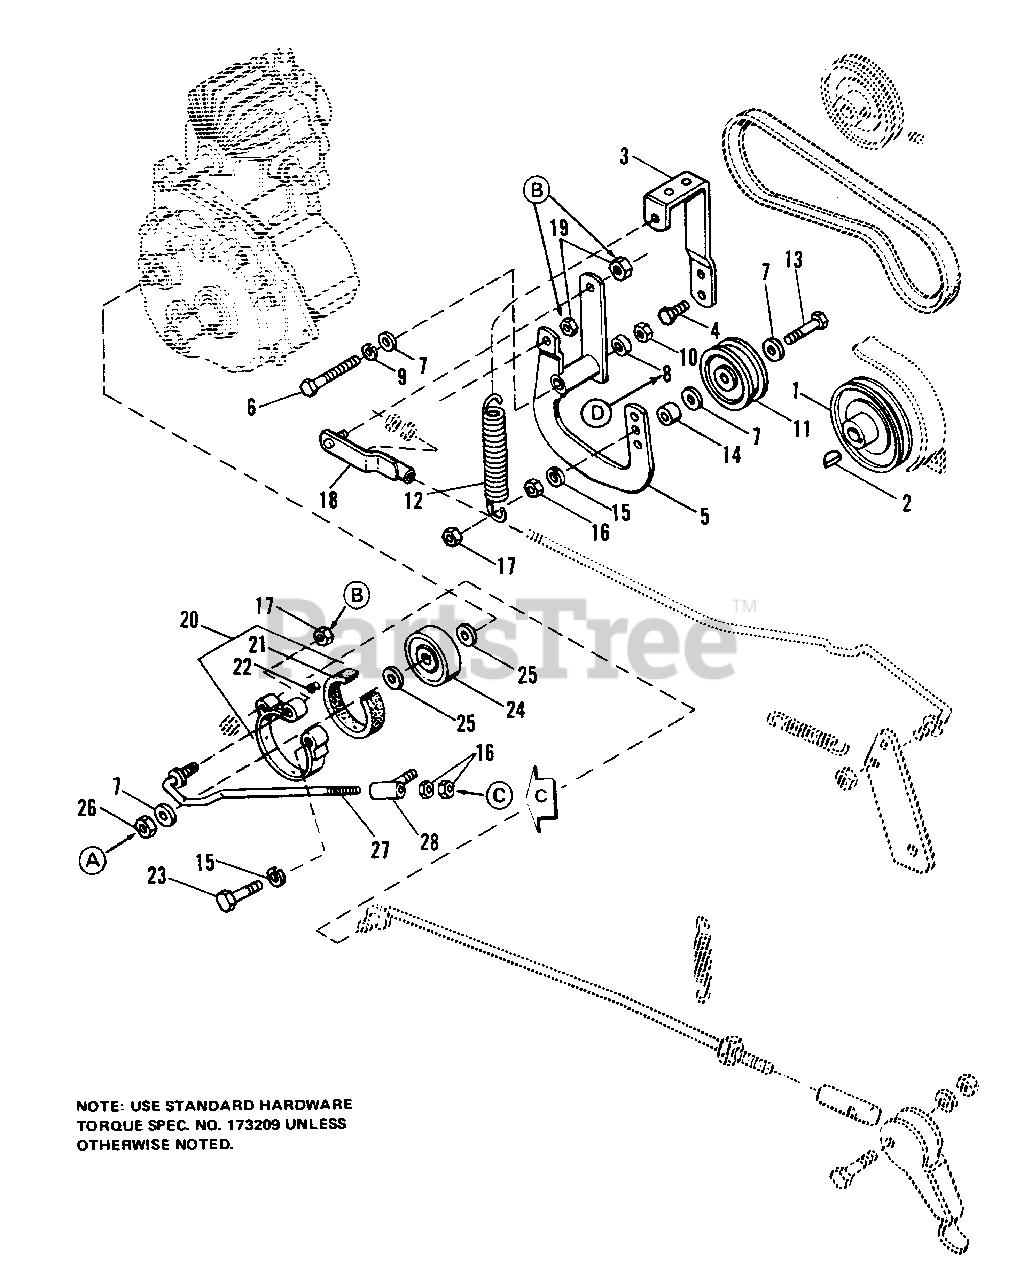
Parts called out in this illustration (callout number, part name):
1	PULLEY
2	KEY
4	SCREW, Thd. Form., 3/8 x 3/4
5	LEVER ASSY, Idler
6	CAPSCREW, Hex Hd., 7/16-14 x 3-3/4
7	WASHER, 3/8 Std.
9	LOCKWASHER, 7/16
10	NUT, Hex, Full, 7/16-14
11	PULLEY, Idler
13	CAPSCREW, Hex Hd., 3/8-16 x 2 1/2
15	LOCKWASHER, 3/8
16	NUT, Hex, Full, 3/8-16
17	NUT, Lock, Hex, 3/8-16
18	GUIDE ASSY
19	NUT, Lock, Hex, 5/16-18
20	BAND ASSY, Brake
21	LINING, Brake
23	CAPSCREW, Hex Hd., 3/8-16 x 1-3/4
24	DRUM, Brake
25	WASHER, Special
26	NUT, Lock, Hex, 7/16-14
28	GUIDE ASSY, Rod
